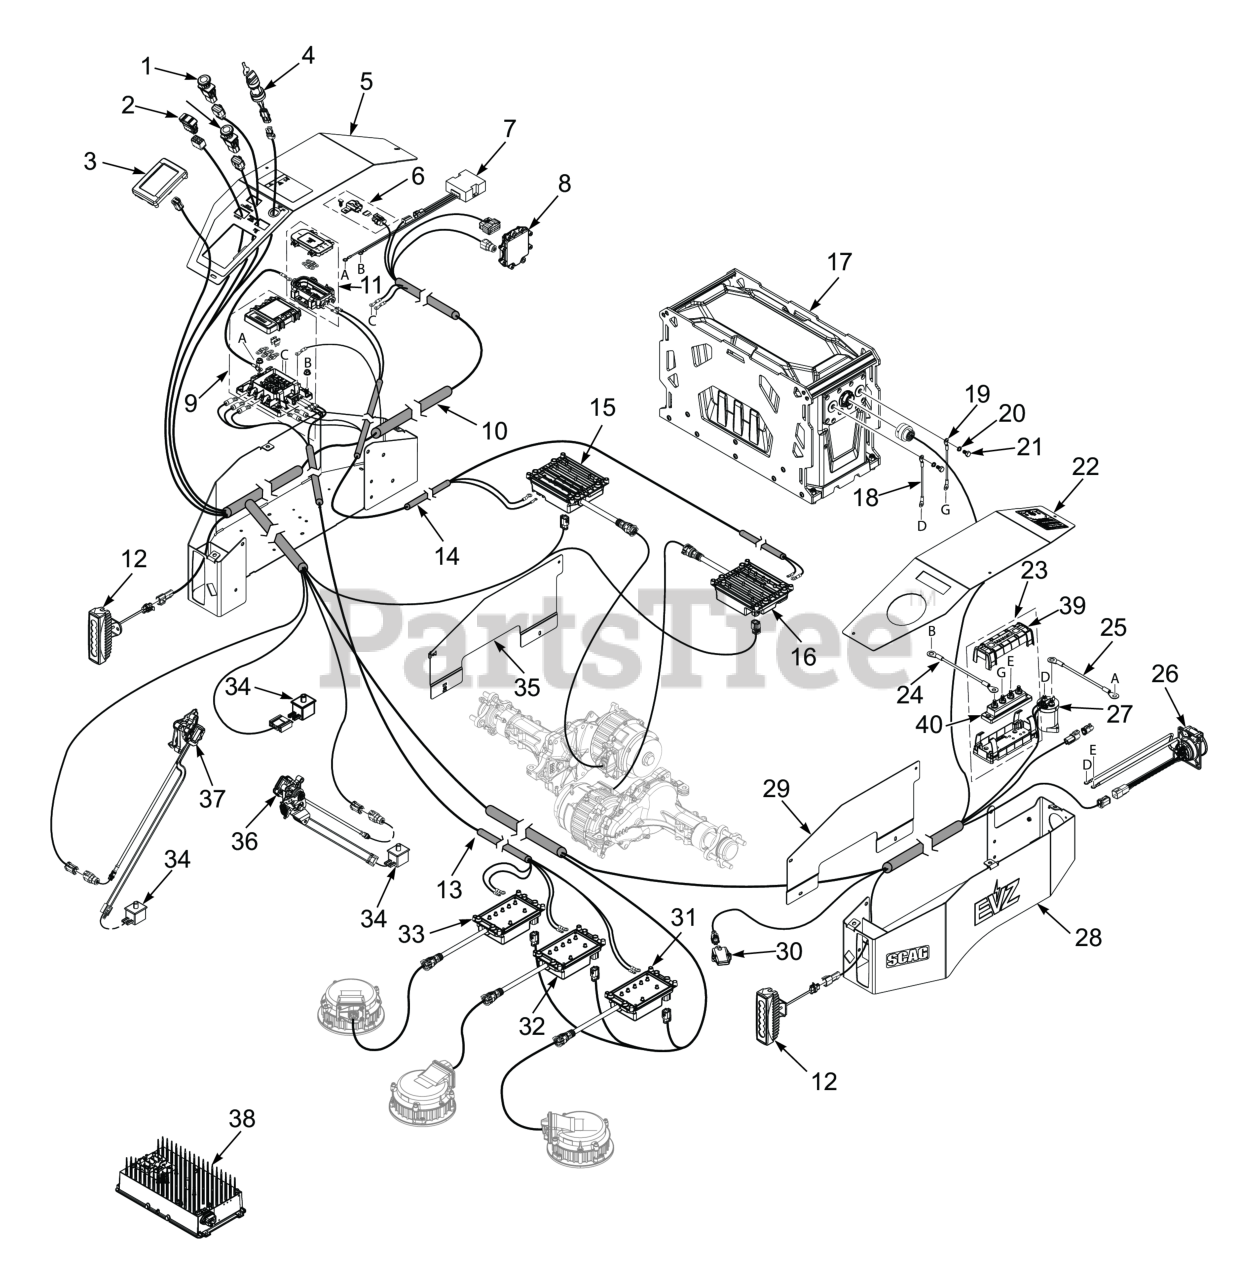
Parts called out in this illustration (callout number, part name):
1	Switch, Emergency Stop
2	Switch, Rocker
3	Display, Insturment Panel
4	Switch, Key
5	Cover w/ Decals, RH Console
6	Single Fuse Assy., Excluding Fuse
7	Converter, 48V to 12V
8	Interface Module
9	Bus Bar
10	Wire Harness, Main
11	Fuse Module
12	Worklight, 48V LED
13	Wire Harness, Deck Controllers
14	Wire Harness, Drive Controllers
15	Drive Controller, RH
16	Drive Controller, LH
17	Battery, 5KW Vanguard
18	Battery Cable, Red 36"
19	Battery Cable, Black 33"
20	Lockwasher
21	Bolt, Stainless Steel
22	Cover w/Decals, LH Console
23	Bus Bar Assy, 4 Post (incl. 39 & 40)
24	Battery Cable, Black 40"
25	Battery Cable, Red 70"
26	Receptacle, Vehicle Plug
27	Relay
28	Console w/Decals, LH
29	Cover, Side LH
30	Blue Tooth, Smart Tec
31	Deck Controller, LH
32	Deck Controller, Center
33	Deck Controller, RH
34	Switch, Double Pole - Plunger
35	Cover, Side RH
36	RTN Assembly, LH
37	RTN Assembly, RH
38	Charger w/Cord
39	Enclosure, Bus Bar
40	Bus Bar, 4 Post
